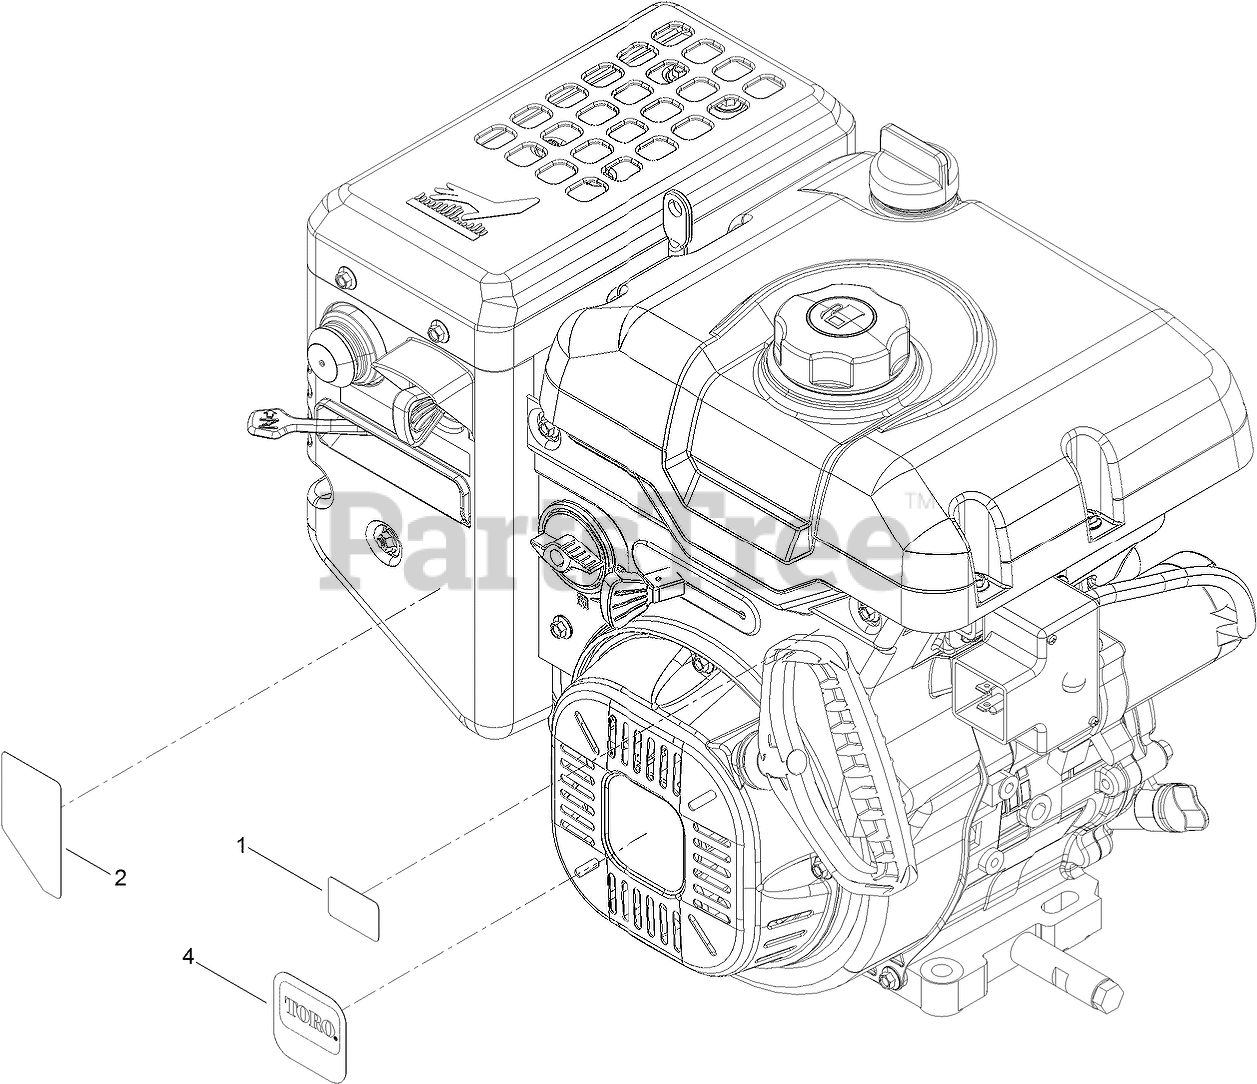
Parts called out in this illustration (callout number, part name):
1	DECAL-THROTTLE
2	DECAL-CONTROL, ENGINE
4	DECAL-RECOIL
